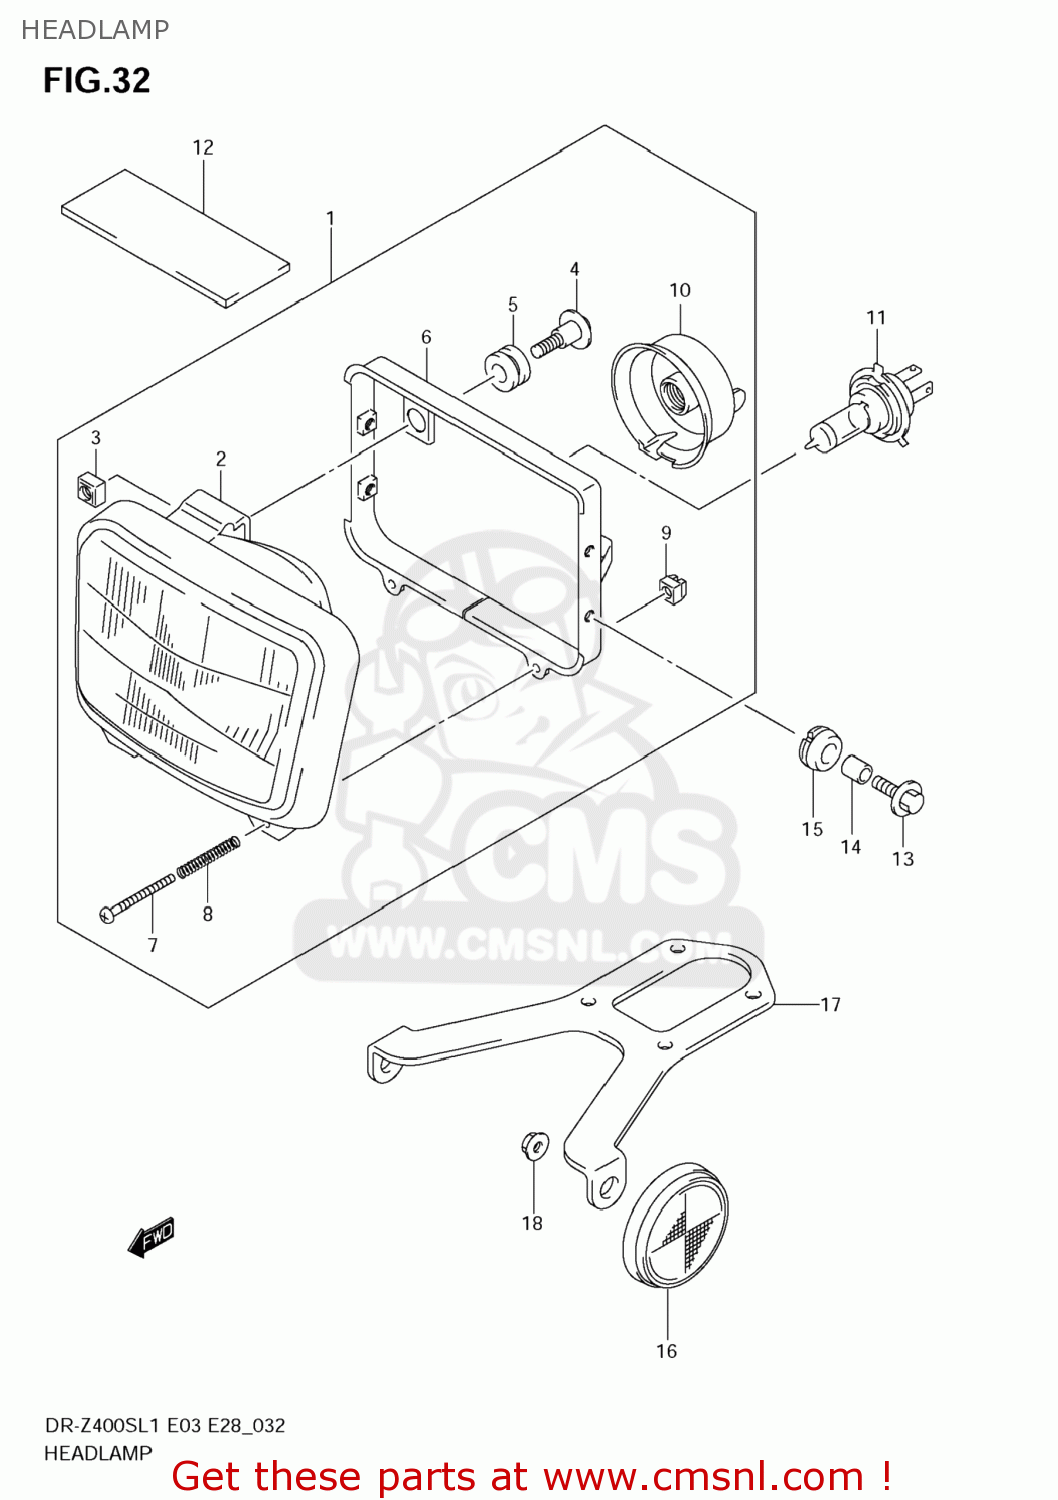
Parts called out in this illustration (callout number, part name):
1	HEADLAMP ASSY
2	UNIT ASSY
3	NUT
4	SCREW,MOUNTING
5	CUSHION
6	HOUSING
7	SCREW,ADJUSTING
8	SPRING,ADJUSTING
9	NUT,ADJUSTING
10	COVER,SOCKET
11	BULB(12V60/55W,H4)
12	PROTECTOR,WIRING HARNESS
13	BOLT(6X20)
14	SPACER(6.5X10X10)
15	CUSHION
16	REFLECTOR,REFLEX
17	BRACKET,FR SIDE RR
18	NUT
